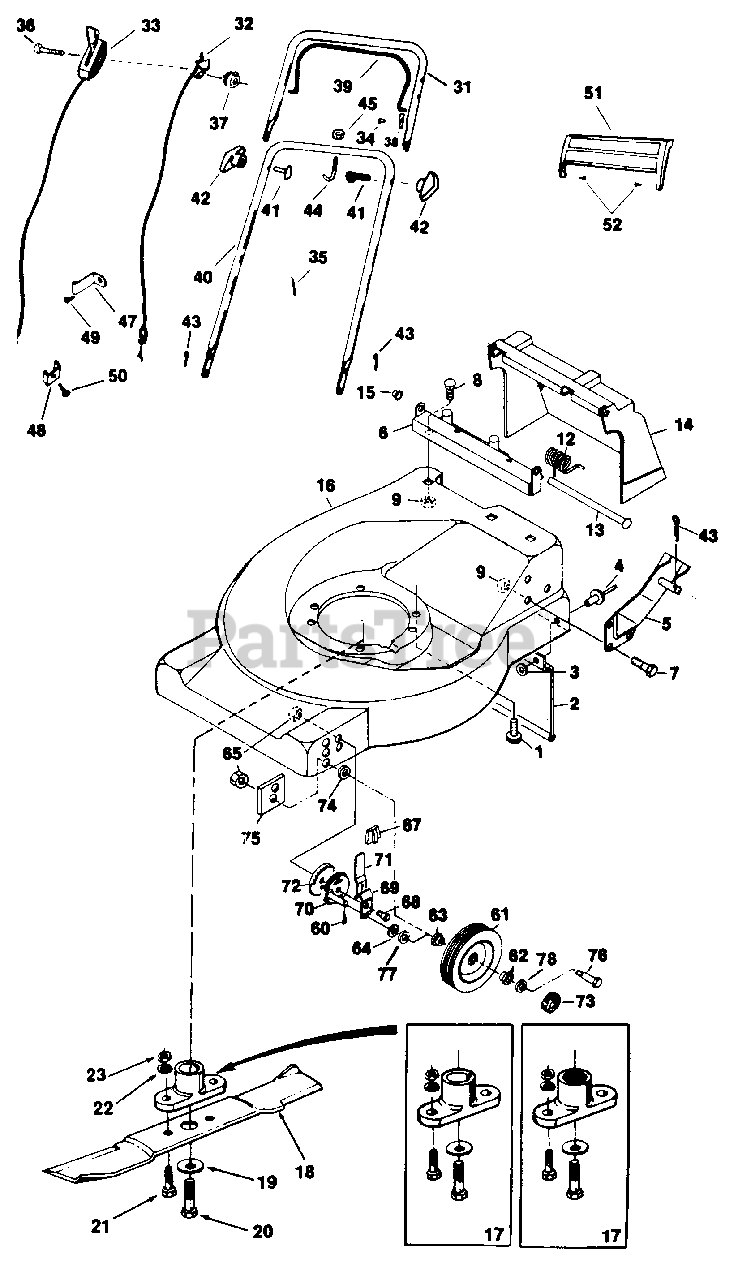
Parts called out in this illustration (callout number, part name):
1	Engine Mounting Bolt
2	Trail Shield
3	Fl-Wash. 3/16" I.D.
4	Blind Rivet
5	Handle Bracket Ass'y.
6	Mount Bracket - Grass Catcher
7	Hex Bolt 5/16-18 x 5/8" Lg.
8	Carriage Bolt 5/16-18 x 3/4" Lg.
9	Hex Keps Nut 5/16-18 Thd.
12	Spring - Rear Door
13	Hinge Pin - Rear Door
15	Retainer
16	21" Steel Deck Ass'y.
17	Blade Adapter Kit
18	21" Blade
19	Bell-Wash. .39" I.D. x 1.14" O.D. (Keyed)
20	Hex Bolt 3/8-24 x 1 1/2" (Keyed)
21	Hex Bolt 3/8-24 x 1" Lg.
22	L-Wash. 3/8" I.D.
23	Hex Nut 3/8-24 Thd.
31	Upper Handle
32	Brake Cable
33	Throttle Control
34	Tapping Screw #10-32 x 1/2" Lg.
35	Plastic Tie
36	Hex Bolt 1/4-20 x 2" Lg.
37	Hex L-Nut 1/4-20 Thd.
38	R.H. Bail Stop Bracket
39	Engine Control Lever
40	Lower Handle
41	Saddle Bolt 5/16-18 x 2" Lg.
42	Knob - Handle
43	Cotter Pin 1/8" x 3/4" Lg.
44	Rope Guide J-Bolt
45	Hex Keps Nut 1/4-20 Thd.
47	Guide Bracket - Cable
48	Clamp-Throttle Cable
49	Tapping Screw #10 x 5/8" Lg.
50	Hex Screw #10 x 5/8" Lg.
51	Trim Panel
52	Tapping Screw #10-32 x 1/2"
60	Cotter Pin 1/8 x 3/4" Lg.
61	8 Marlex Wheel
62	Nylon Outer Bearing
63	Nylon Inner Bearing
64	Flat Washer 1/2" I.D.
65	Hex L-Nut 3/8-16 Thd.
67	Adjuster Knob
68	Shoulder Bolt
69	Sprinq - Adjuster
70	Disc & Pin Ass'y. - Adjuster
71	Lever - Adjuster
72	Inner Plate - Adjuster
73	Hub Cap
74	Spacer
75	Support Plate
76	Wheel Bolt
77	Spacer- Plastic
78	Washer- Hub Cap
